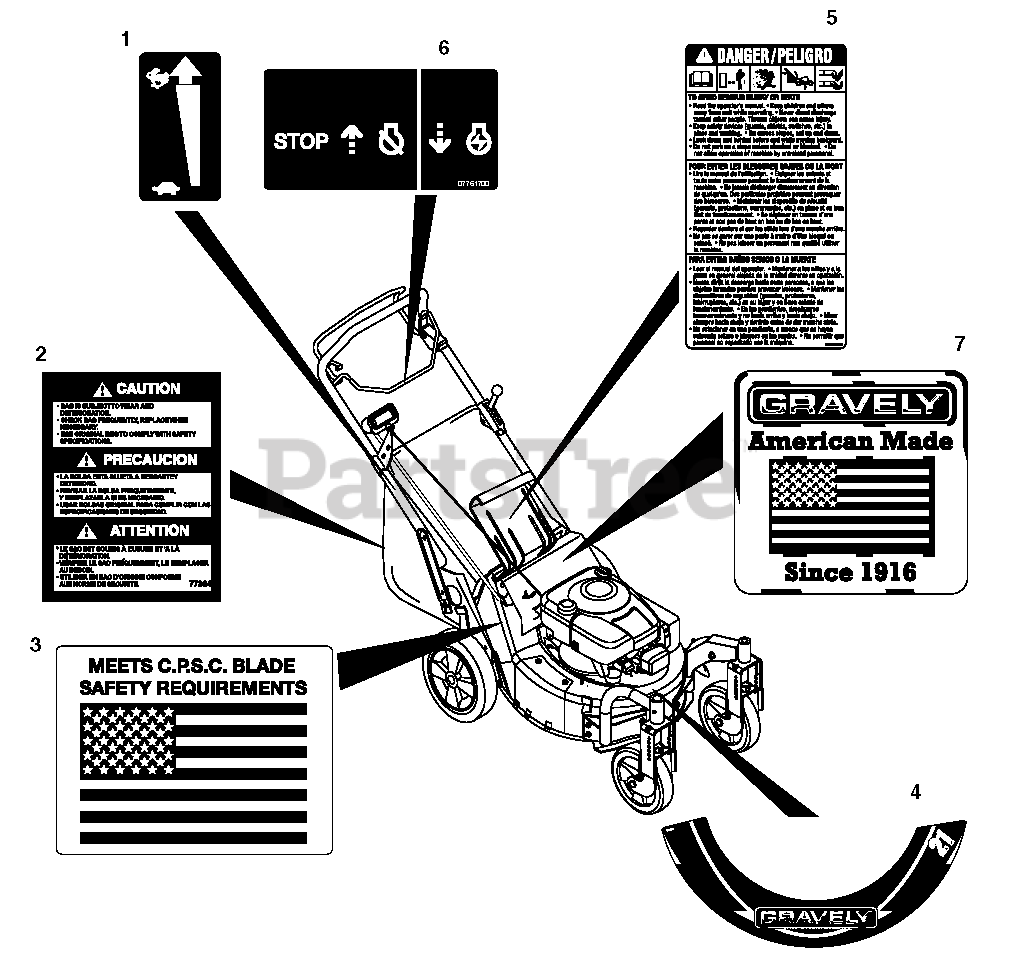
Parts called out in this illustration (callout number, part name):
1	Decal, Speed Control
2	Label, Bagger 21"
3	Decal, Ariens Deck
4	Decal, Bilingual Danger
5	Decal, Engine Control
6	Decal, CPSC/USA Flag
7	Decal, American Made Ariens
